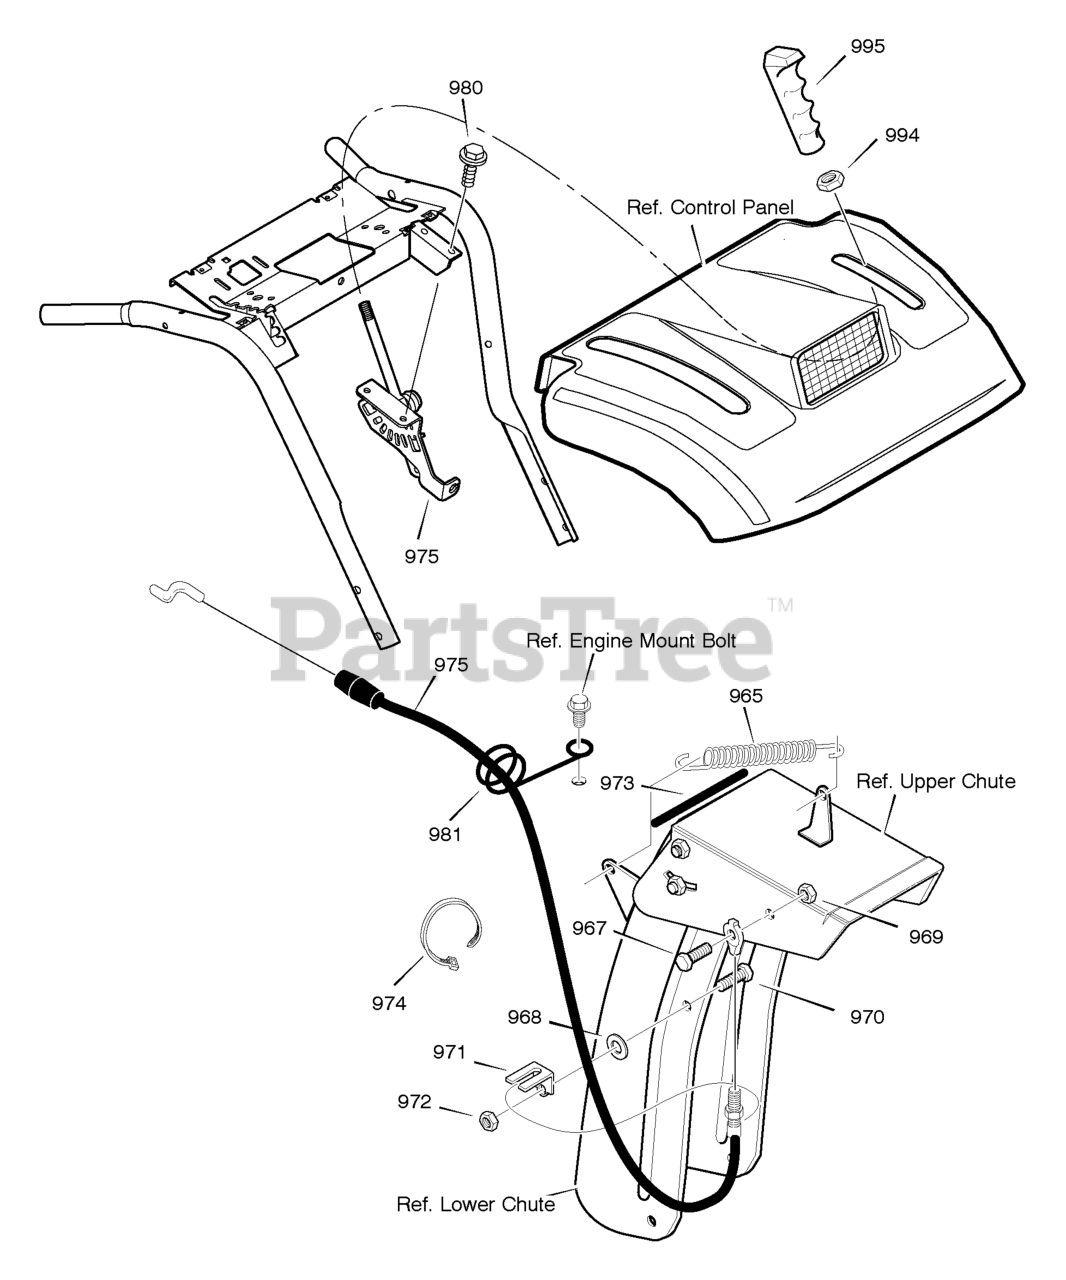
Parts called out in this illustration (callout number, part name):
965	TENSION SPRING
967	BOLT, SHOULDER
968	FLATWASHER
970	SCREW, 5/16-18 x 0.75
971	BRACKET, CABLE CHUTE
972	NUT, 5/16-18
973	TRIM STRIP, BLACK
974	TIE, CABLE
975	CABLE, CHUTE DEFLECTOR
980	SCREW
981	WIRE FORM, CHUTE CABLE
994	NUT, 3/8-16
995	KNOB, SHIFT
